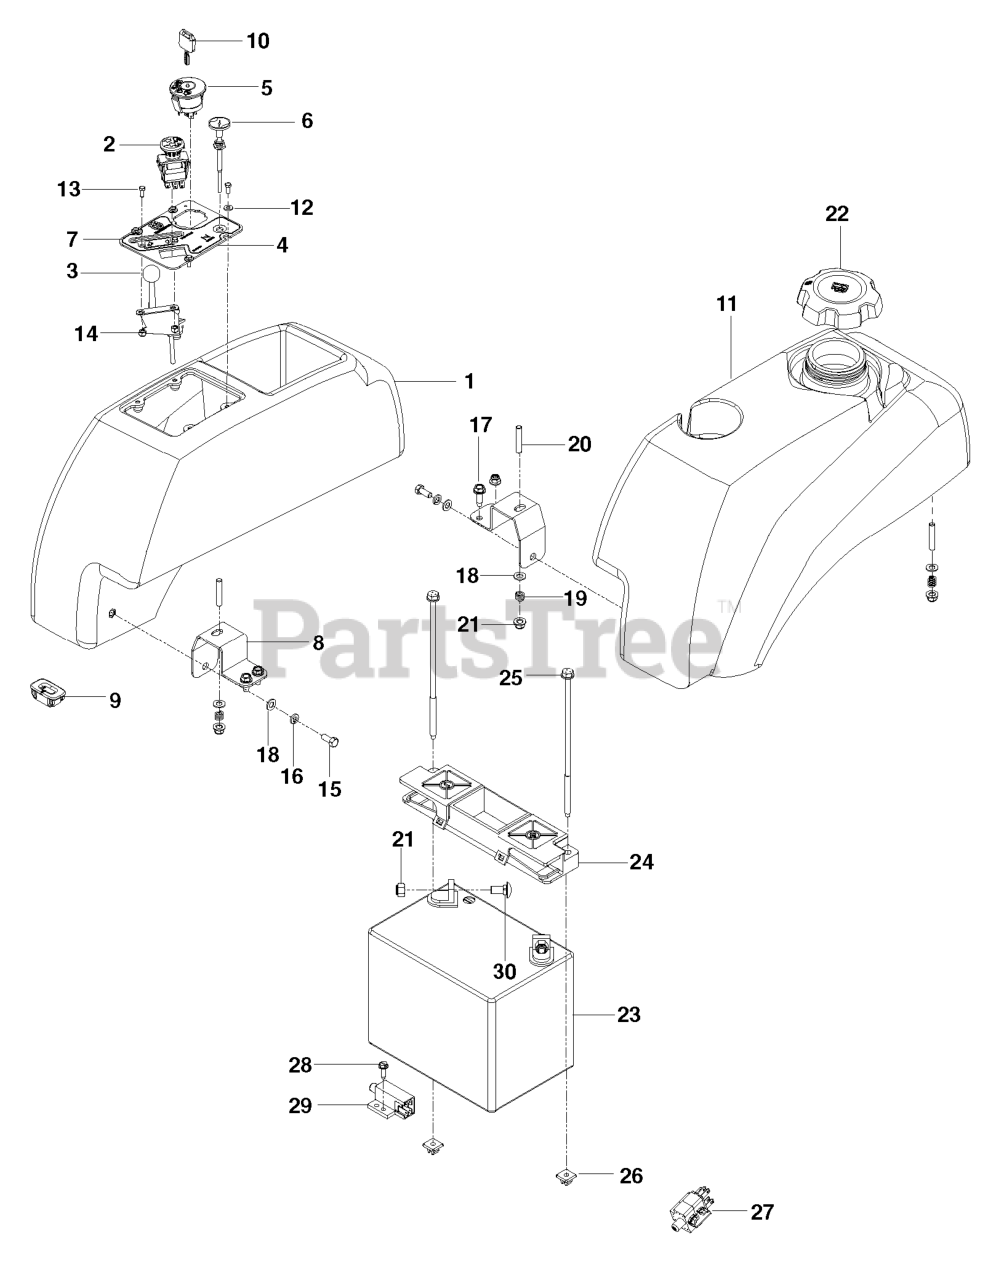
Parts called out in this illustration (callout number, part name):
1	FENDER CONSOLE
2	RP SWITCH.PTO.TERMINAL.STD.RED
3	THROTTLE CABLE
4	CONSOLE PLATE, BLACK
5	RP IGNITION SWITCH
6	CONTROL-CHOKE 57"
7	DECAL, CONSOLE
8	SUPPORT, TANK, BLK
9	HOUR METER
10	KEY
11	LEFT TANK W/CUP HOLDER
12	WASHER #10
13	HCS #10-24 X 1/2
14	NUT 10-24 NYLOC
15	HCS 5/16C X 3/4
16	WASHER.LOCK.HVY.HLCL.SPR.5/16
17	RP BLT 5/16-18 X 1 THRD FORM D
18	FLAT WASHER 5/16 SAE
20	STUD, 5/16C
21	5/16-18 NYLOC FLANGE NUT
22	FUEL CAP, HTC
23	BATTERY, 12 V 330 AMP
24	BATTERY HOLD DOWN
25	BOLT - 1/4-20 X 7.5
26	PUSH NUT-NYLON
27	SWITCH, INTERLOCK
28	SCREW #10 X 1/2 SELF TAPPING
29	SWITCH, BRAKE 3P
30	BOLT 5/16C X 3/4" CARRIAGE
